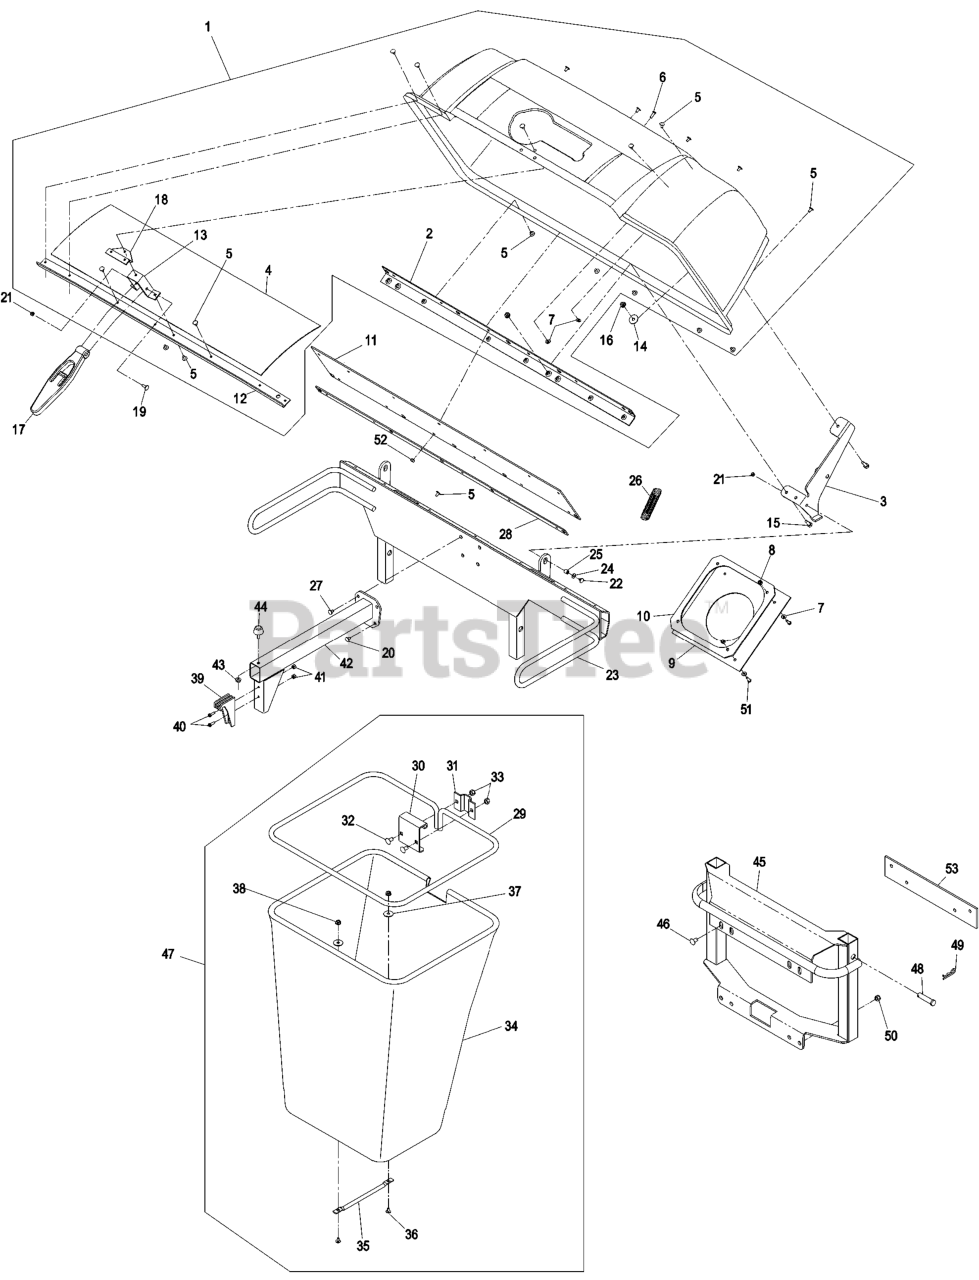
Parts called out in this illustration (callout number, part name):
1	ASM, HOOD
2	STIFFENER-BAGGER, TOP
3	HINGE ASM
4	SCREEN-BAGGER
5	RIVET-BLIND
6	SCREW-HEAD, TRUSS
7	WASHER-FLAT
8	NUT-LOCK, NI
9	SEAL-CHUTE
10	CLAMP-SEAL
12	SUPPORT-SCREEN
13	ANCHOR-LATCH
15	SCREW-HH
18	REINFORCEMENT-LATCH
19	SCREW-HH
20	SCREW-HH
21	NUT-LOCK, NI
22	SCREW-HH
23	BAGGER UPRIGHT ASM
24	WASHER-FLAT
26	SPRING-EXTENSION
27	SCREW-HSBH
28	PLATE-BACKING
29	FRAME-BAG
30	HANGER-BAG
32	BOLT-CARR
33	NUT-LOCK, NI
35	HANDLE-BAG
36	BOLT-CARR
38	NUT-LOCK, NI
40	SCREW-PPH
42	SUPPORT-BAG
45	BAGGER MOUNT ASM
46	SCREW-HH
48	PIN-CLEVIS
49	PIN-COTTER
51	SCREW-PPH
52	NUT-LOCK, SIDE
53	SPACER,COUNTERWEIGH
